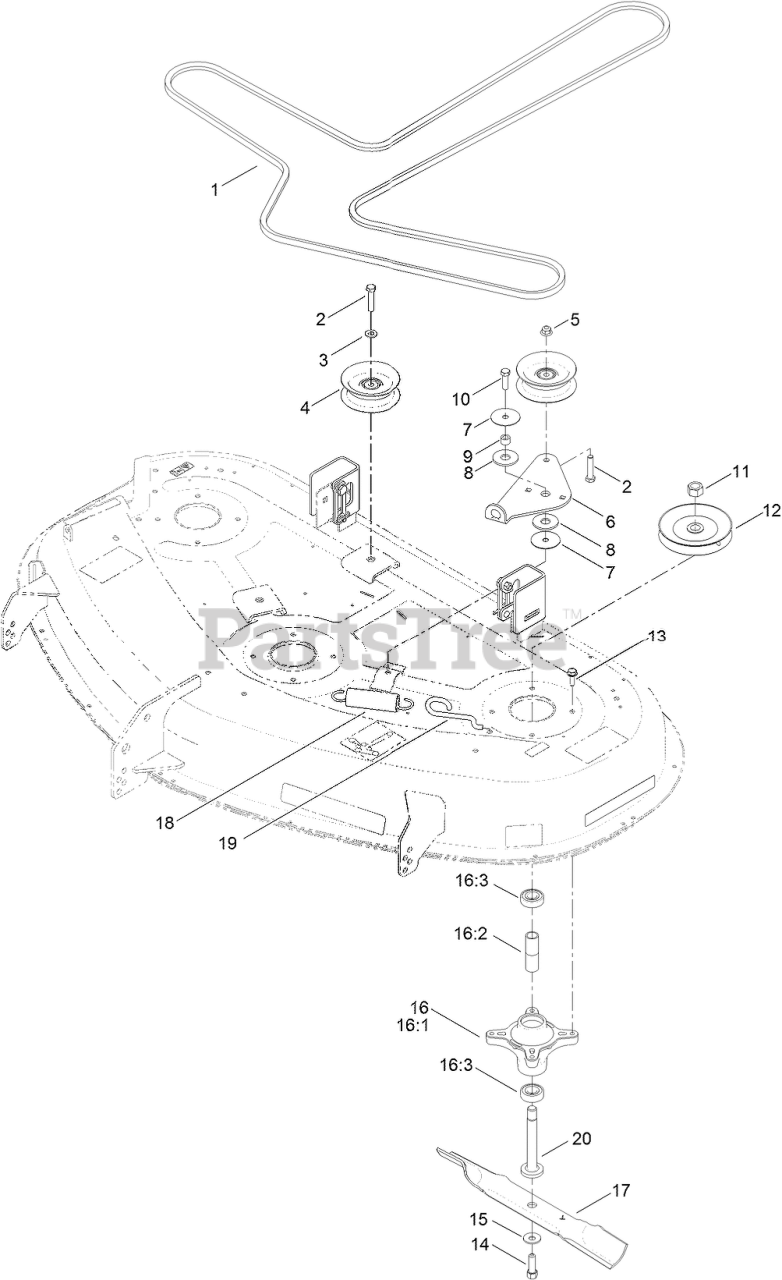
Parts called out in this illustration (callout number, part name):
1	V-BELT
2	SCREW-HH
3	WASHER-FLAT
4	PULLEY-IDLER, FLAT
5	NUT-HF, NI
6	ARM-IDLER
7	WASHER
8	WASHER-FRICTION, COMPOSITE
9	SPACER
10	SCREW-HH
11	NUT-HEX
12	PULLEY
13	SCREW-TAPTITE
14	SCREW-HH
15	WASHER-BELLEVILLE
16	SPINDLE ASM
16:1	SPINDLE
16:2	SPACER
16:3	BEARING-BALL
17	BLADE-MULCH, 17.50 INCH
18	SPRING-EXTENSION
19	HOOK-RETURN, SPRING
20	SHAFT-SPINDLE
